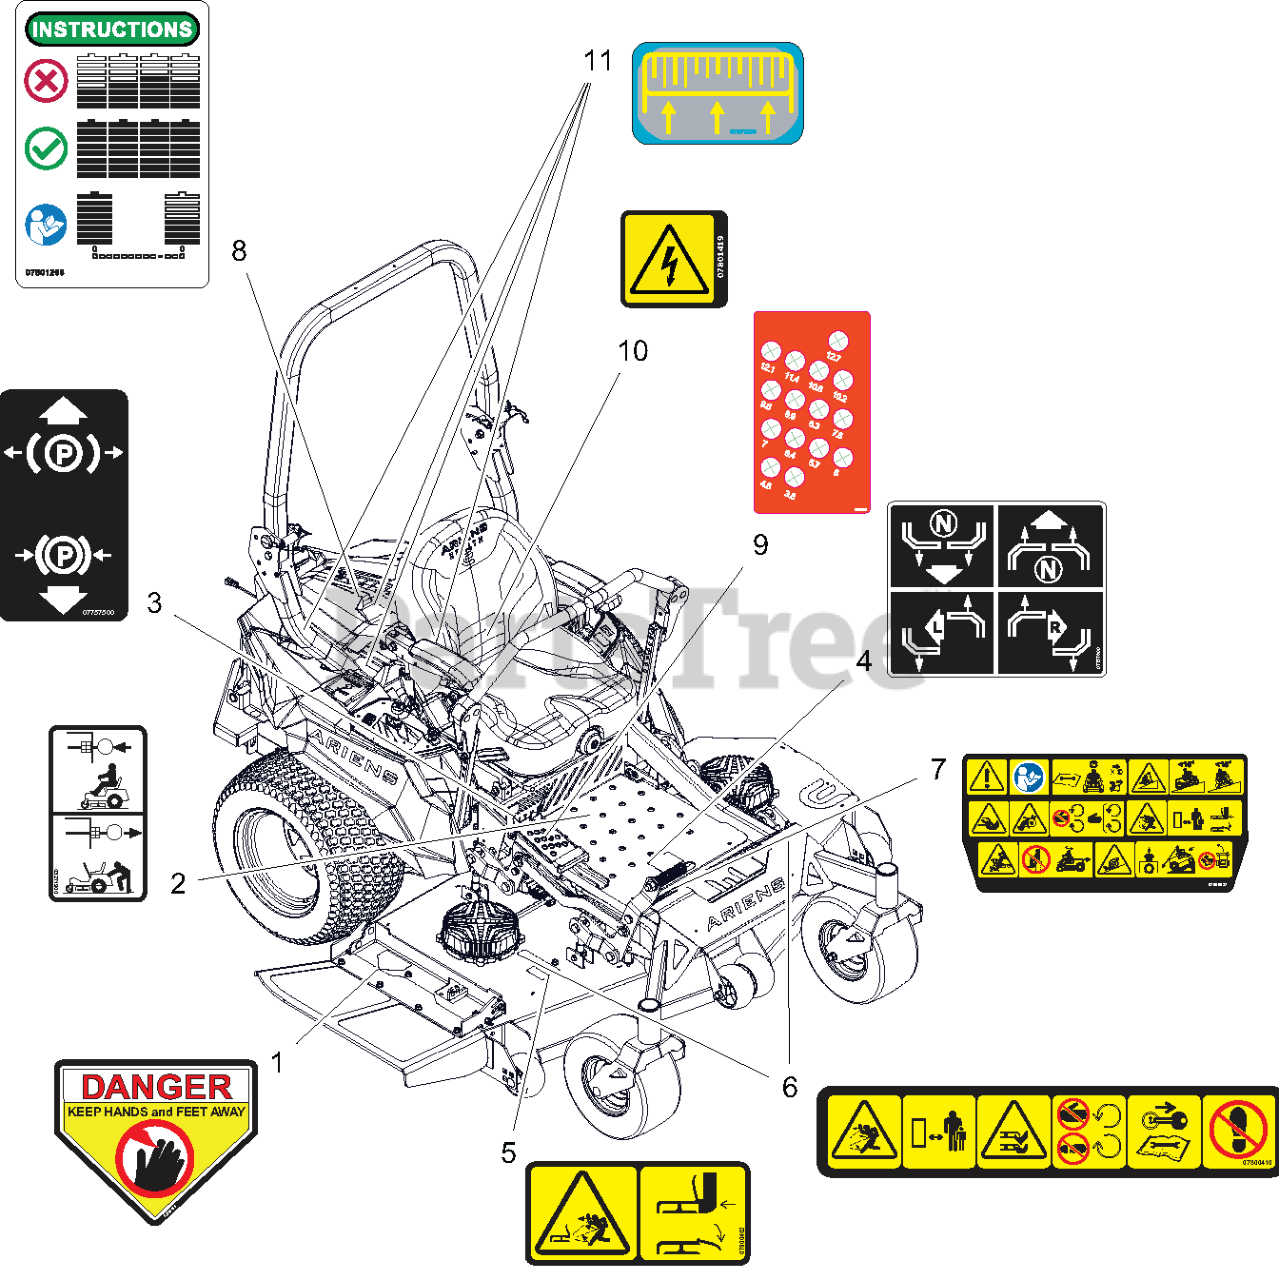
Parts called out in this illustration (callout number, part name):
1	DECAL, DANGER
2	DECAL, TRANSMISSION DISCONNECT
3	DECAL, PARKING BRAKE LEVER
4	DECAL, INSTRUCTIONAL-STEERING
5	DECAL, SAFETY - DECK GUARDING
6	DECAL, DECK SAFETY
7	DECAL, MAIN SAFETY
8	DECAL, BATTERY BALANCE
9	DECAL, APEX HOC METRIC
10	DECAL, SAFETY - DANGER
11	DECAL, BATTERY INSTALL DIRECTION
